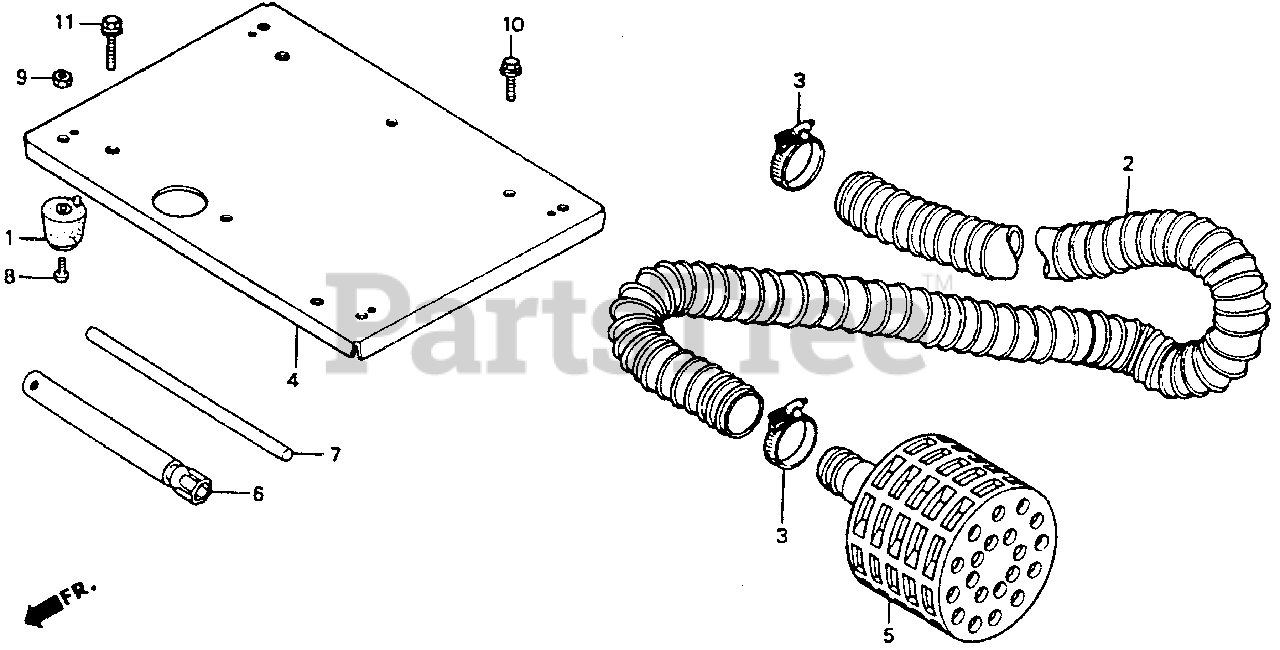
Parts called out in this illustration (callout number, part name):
1	RUBBER (LOWER)
2	HOSE, SUCTION
3	BAND, HOSE
4	BED, FRAME
5	STRAINER
5	STRAINER Use from Frame SN 1582886.
6	WRENCH, SPARK PLUG
7	HANDLE, BOX WRENCH
8	SCREW, PAN (6X10)
9	NUT, HEX. (6MM)
10	BOLT, FLANGE (8X20)
10	BOLT, FLANGE (8X25)
11	BOLT, FLANGE (8X28)
